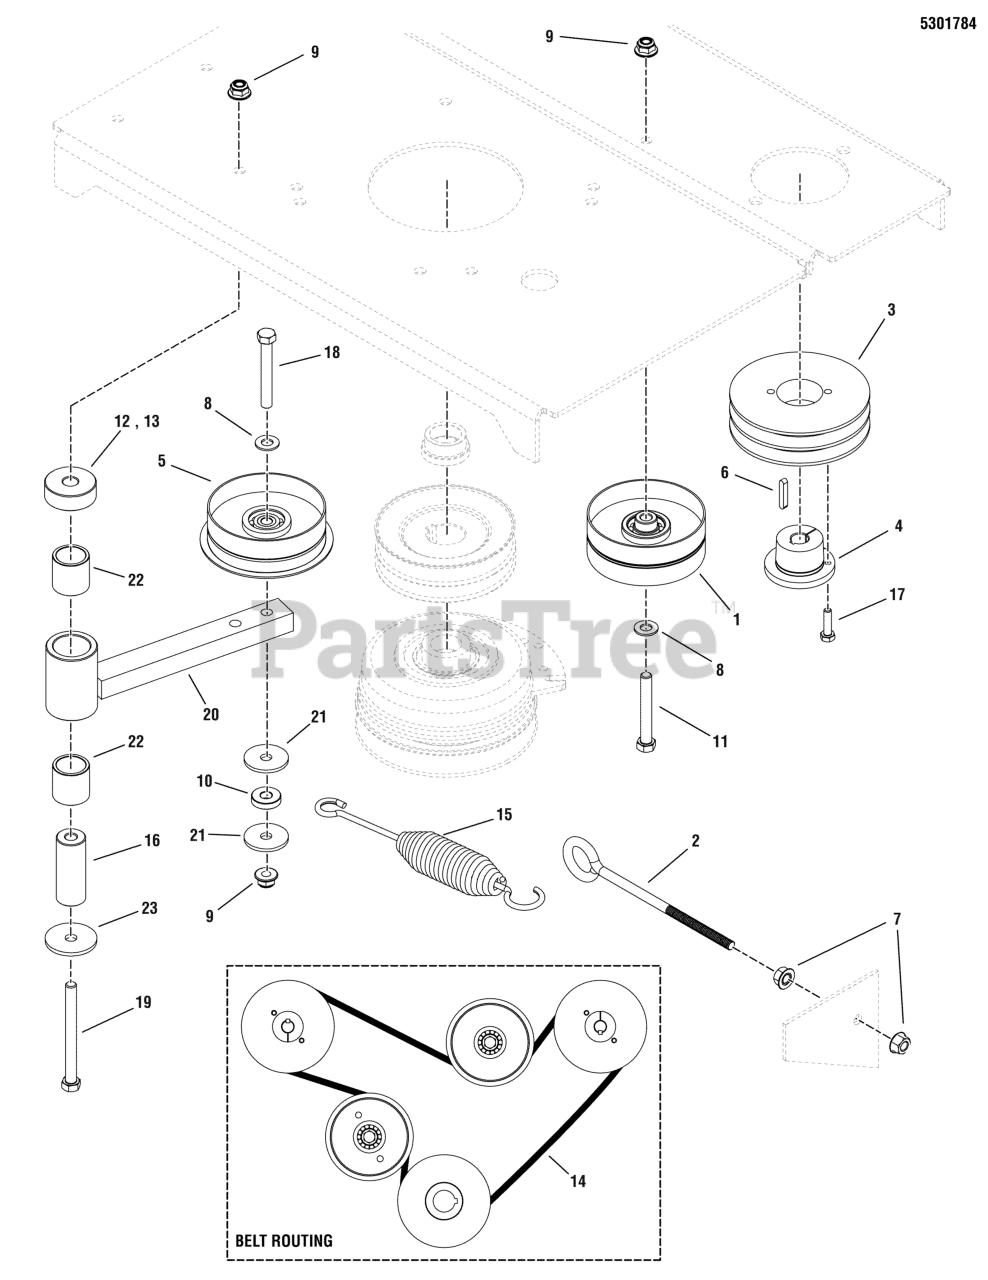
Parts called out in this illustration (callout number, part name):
1	PULLEY-IDLER, 5.00OD, .385ID, 1.50W STL
2	EYE BOLT, 3/8-16 X 8, 1 EYE
3	PULLEY, PUMP DRIVE
4	BUSHING, TAPERED HUB
5	PULLEY, IDLER, SINGLE FLANGE
6	KEY, 5MM SQ. W/ RADIUS
7	NUT, 3/8-16 HEX SERRATED FLANGE
8	WASHER, 3/8 SAE
9	NUT, 3/8-16 HEX NYLOCK FLANGE
10	SPACER, .39 X 1.00 X .25
11	BOLT, 3/8-16 X 2, GD5, CZ
12	SPACER, .45 X 1.88 X .38
13	SPACER, .51 X 1.75 X .63
14	BELT, BANDED A-SEC,64.76EL,POLY,RAW EDGE
15	SPRING, EXTENSION, SWIVEL. LONG HOOK
16	SPACER, .39 X 1.000 X 2.55, SS
17	BOLT, 1/4-20 X 1" GD5 CZ
18	BOLT, 3/8-16 X 2-3/4" GD5 CZ
19	BOLT, 3/8-16 X 4" GD5 CZ
20	See "PUMP DRIVE [Cast Idler Arm for replacing Steel Pump Drive Idler Arm]"
21	WASHER, .390 X 1.50 X .109, YZ
22	BUSHING, BRASS, 1.25X1X1.25
23	WASHER, .41 X 1.75 X .14
